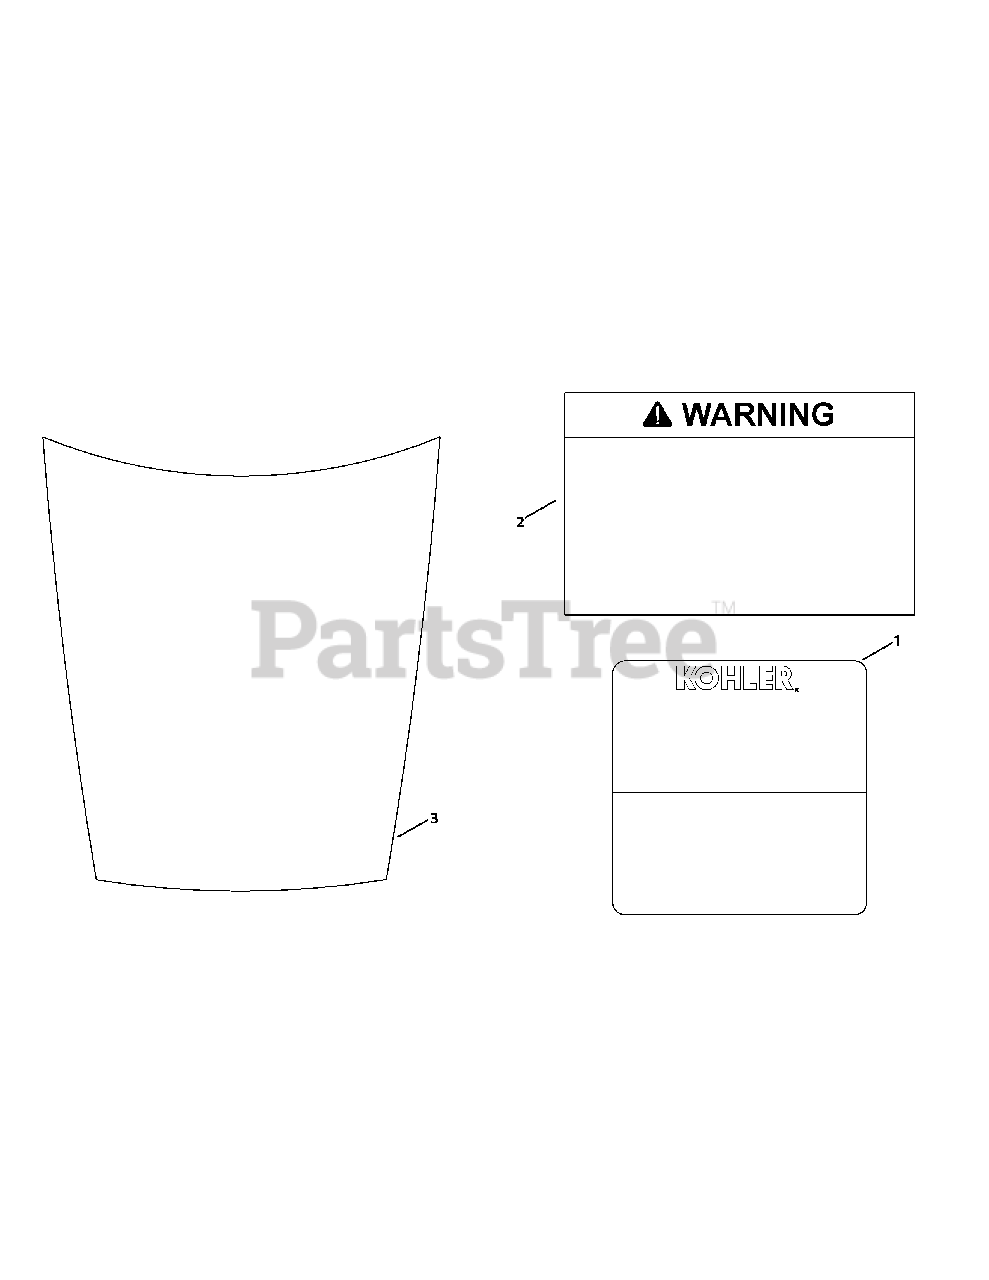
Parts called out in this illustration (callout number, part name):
1	Service Nameplate
2	Warning Decal
3	Name XT8 Decal (Walk Styling)
